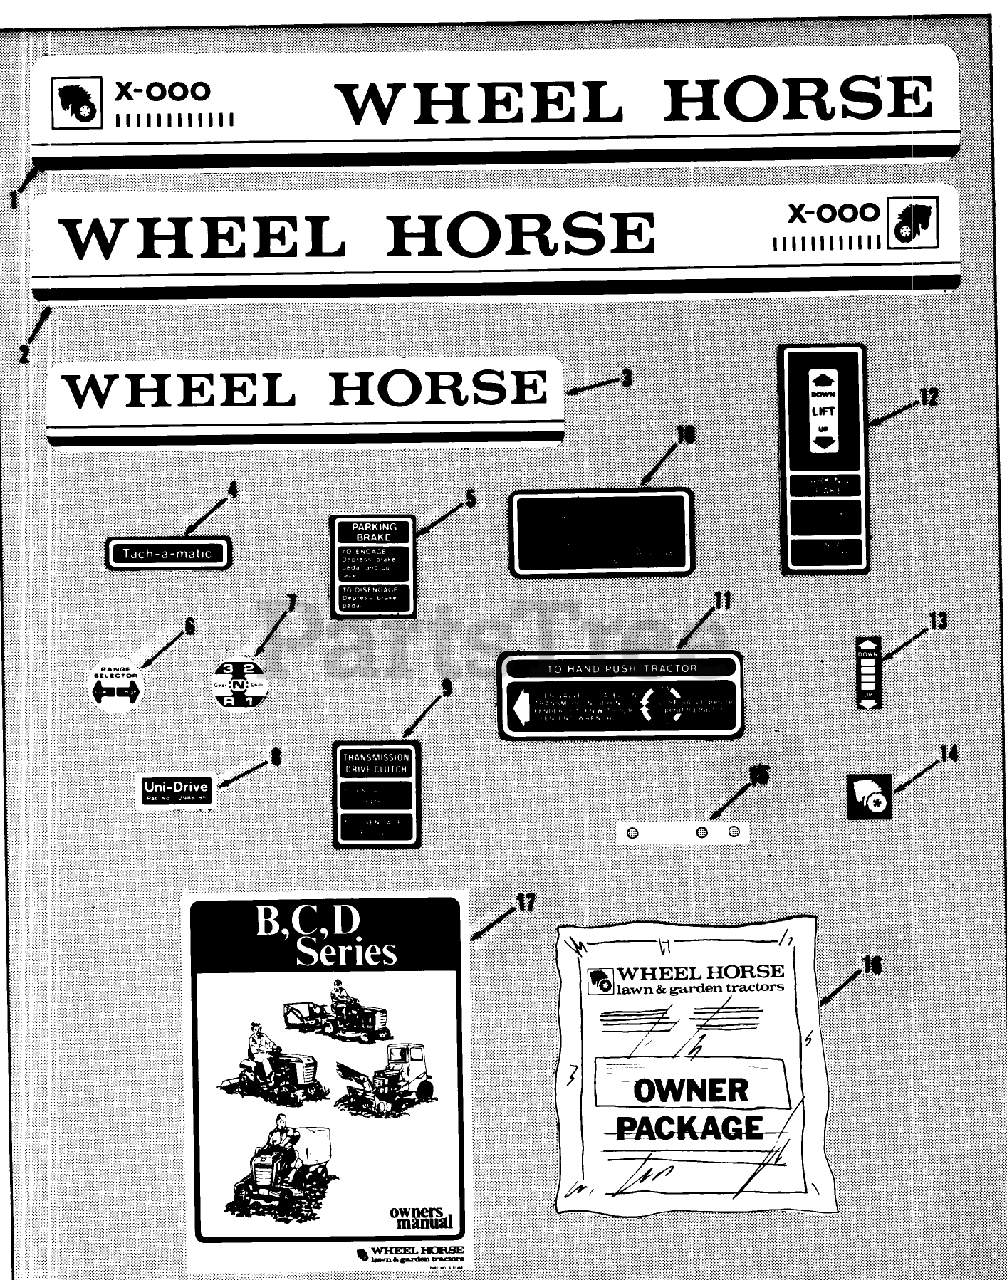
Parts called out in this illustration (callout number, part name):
1	ORDER 101637 R&L DECAL
2	Decal RH C-175 Twin Automatic
2	ORDER 101637 R&L DECAL
3	DECAL-REAR
5	DECAL-PARKING BRAKE
12	Decal-Parking Brake Lift
14	Decal-Hood
15	Decal-Taillight C-165, C-175 Twin Only
16	Loose Parts Package C-105, C-125 Only
16	Loose Parts Package C-145, C-165 Only
16	Loose Parts Package C-175 Twin Only
16	Loose Parts Package C-85 Only
17	TRACTOR OWNER MANUAL
